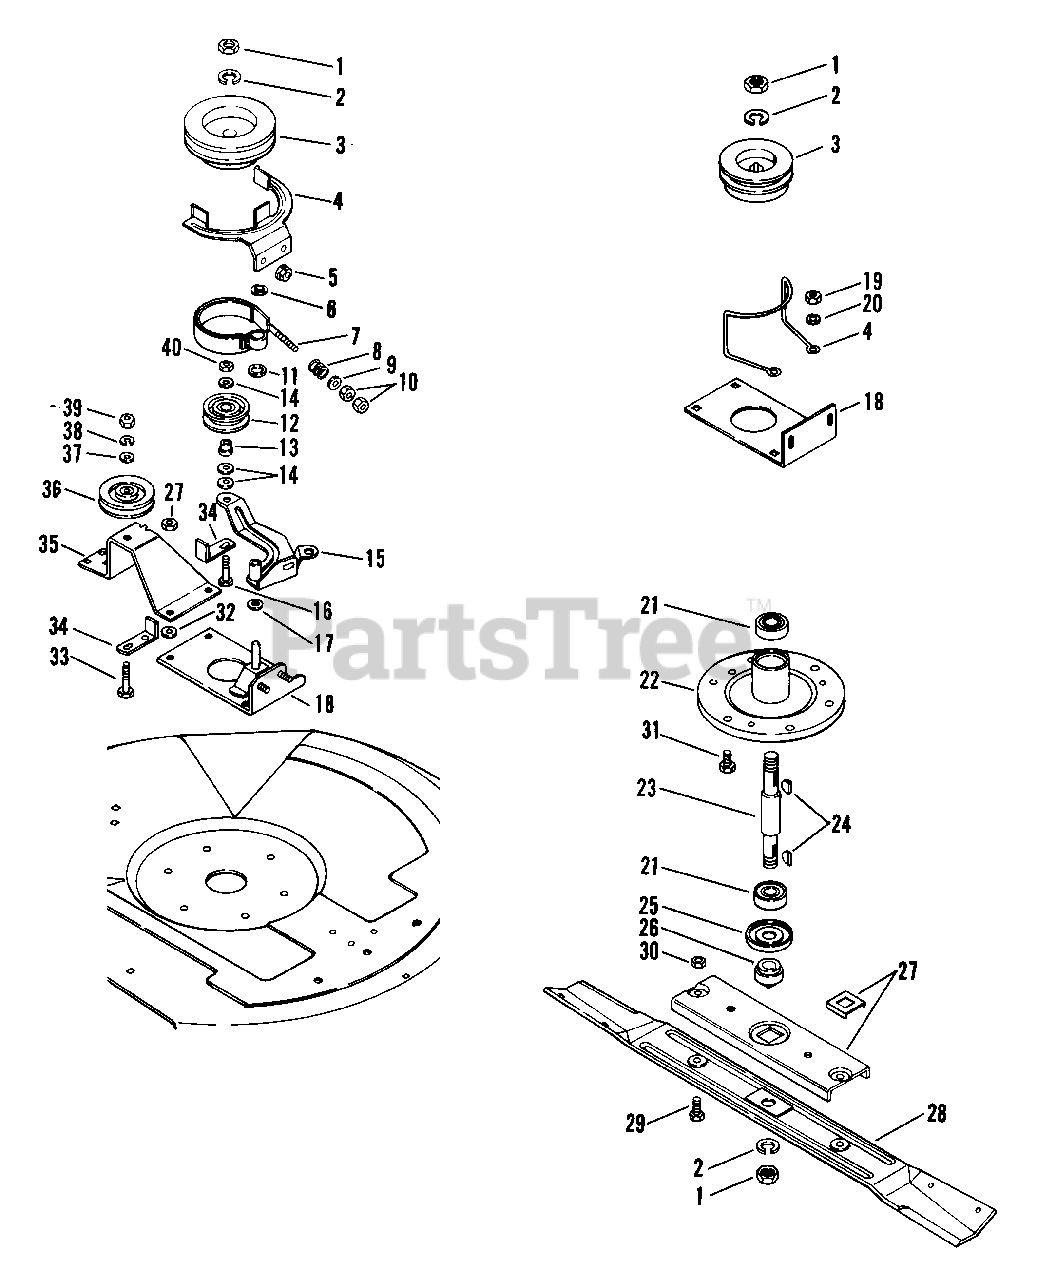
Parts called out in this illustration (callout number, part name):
1	NUT-JAM .75-10 PL
2	WSHR-LK .750X.188 MED PL
3	MOWER SHEAVE
4	BELT FINGER
4	MOWER BELT FINGER
5	NUT-FLG. .312-18 PL
6	FASTENER
7	PAN BRAKE AND IDLER ARM PACKAG
7	BRAKE BAND
8	SG-COMP .072X.687X.75
9	WSHR-FL-STL.344X.688X.065PL
10	NUT-HEX .312-18
11	WSHR-FL-STL .640X1.005X.062 PL
12	IDLER
13	SPCR, BRG .315X.50X.688X.281
14	WSHR-FL-STL .38X.875X.083 PL
15	IDLER ARM
16	BLT-HEX .31-18X1.50 PL GR2
17	WSHR-FL-STL .382X.812X.062
18	PLATE
18	PIVOT PLATE
19	NUT-LK-CTR .375-16 GR A PL
20	WSHR-FL-STL .406X.865X.094 PL
21	BRG-BALL .750X1.781X.61
22	SPINDLE HOUSING
23	SPINDLE SHAFT
24	KEY-WDRF .188X.75X.313 SAE 9
25	BEARING SLINGER
26	RETAINER HUB
27	BLADE TRAY
28	MOWER BLADE 26
28	MOWER BLADE 28
28	MOWER BLADE 30 INCHES
28	MOWER BLADE 32
29	BLT-HEX .38-16X1.00 PL GR5
30	NUT-LK TOP .375-16 GR C YWZC
31	BLT-HEX .38-16X1.00 PL
32	WSHR-FL-STL.406X.812X.065PL
33	BLT-HEX .38-16X1.75 PL GR2
34	BELT FINGER
35	IDLER MOUNT
36	IDLER-V 3.06 X .38
37	WSHR-FL-STL .390X.750X.125 PL
38	WSHR-LK .375X.094 MED PL
39	NUT-HEX .375-16
40	NUT-LK .312-18 GR A PL
